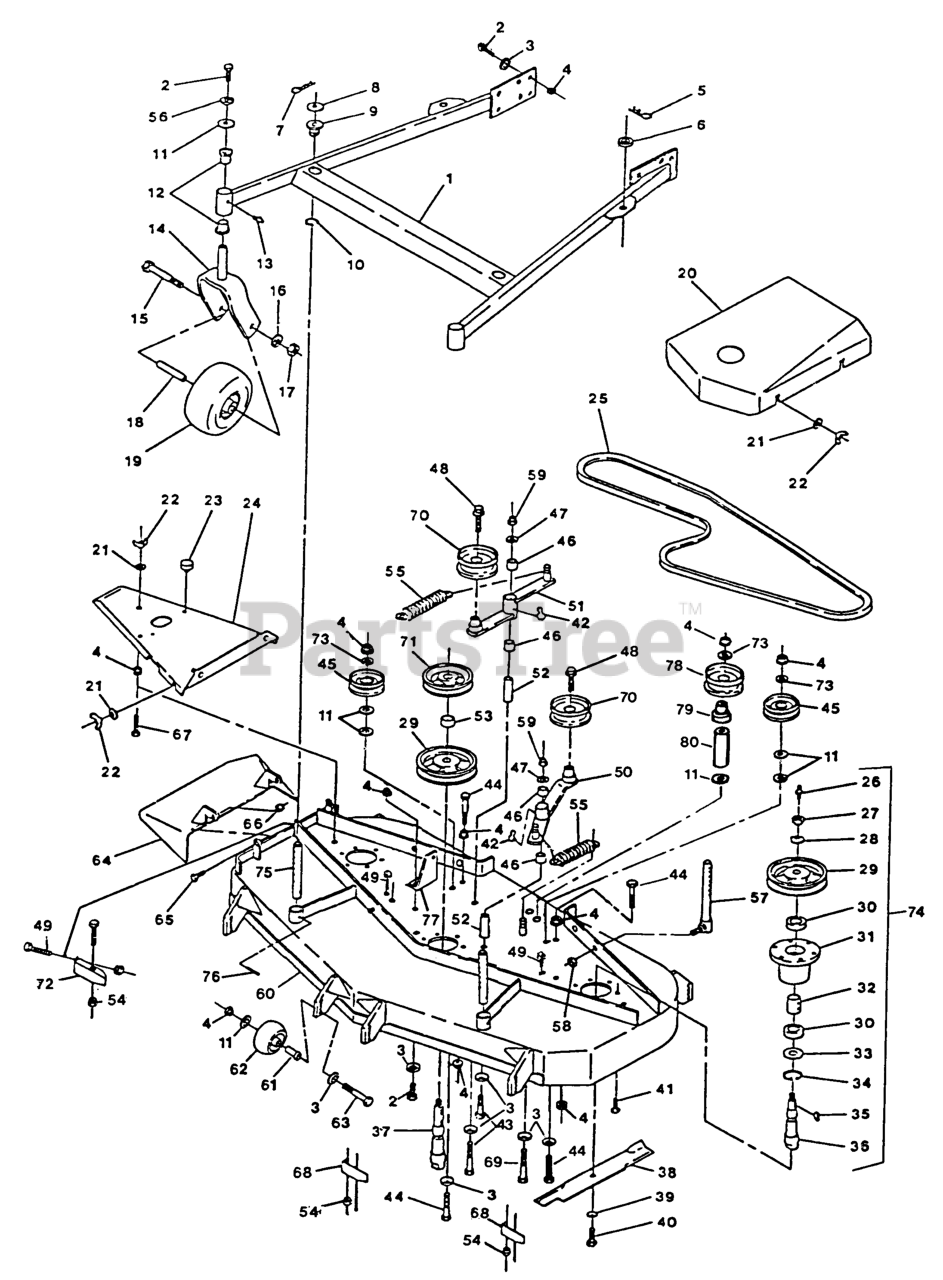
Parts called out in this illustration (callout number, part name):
1	SUPPORT ASSY-FMD60
5	PIN,HAIR COTTER
8	WASHER-FLAT
9	BUSHING-DECK
12	BEARING-FLANGED
22	NUT-WING
24	WLD,DECK COVER
25	BELT-DRIVE, BLADE
28	WASHER-SPRING
29	SHEAVE,BLADE DRIVE
32	SPACER,BEARING
33	SEAL,MECHANICAL DUST
34	RING,SNAP WLDS N5000-244
36	SPINDLE-OUTER BLADE
37	SPINDLE-CENTER BLADE
39	WASHER-SPRING
41	SCRW,TPTTE HH
43	SCREW-HH
45	IDLER,PULLEY
46	SLEEVE-BEARING
50	Arm Weldment Deck Drive Idler
51	Arm Weld - Dk. Idler Arm
52	BUSHING-PIVOT, IDLER
53	SPACER-TUBE
55	SPRING-EXTENSION
61	BUSHING-ROLLER
62	ROLLER-SCALP, ANTI
70	IDLER,PULLEY
72	WLD,BAFFLE DISCHARGE
74	CH-52&60 OUTER CUTTR
75	ROD,DECK SUPPORT
77	BRACKET,SPRING ANCHOR
78	PULLEY-IDLER
79	BUSHING,IDLER
80	SPACER-FENDER
